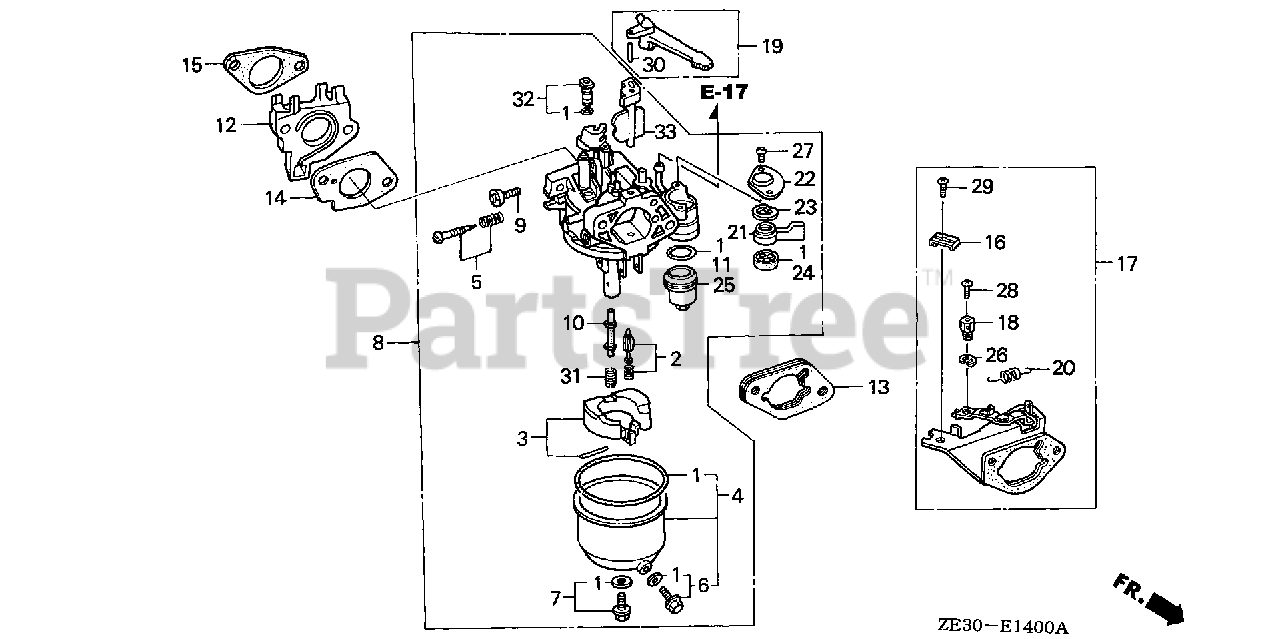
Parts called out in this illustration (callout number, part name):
1	GASKET SET (INCLUDES 16173-001-004)
2	VALVE SET, FLOAT
3	FLOAT SET
4	CHAMBER SET, FLOAT
5	SCREW SET, PILOT
6	SCREW SET, DRAIN
7	SCREW SET
8	CARBURETOR ASSY. (BE30B E)
9	SCREW, THROTTLE STOP
10	NOZZLE, MAIN
11	GASKET, FUEL STRAINER CUP
12	INSULATOR, CARBURETOR
13	SPACER, CARBURETOR
14	GASKET, CARBURETOR
15	GASKET, INSULATOR
19	LEVER, CHOKE (STD)
21	LEVER, VALVE
22	PLATE, LEVER SETTING
23	SPRING, PETCOCK LEVER
24	GASKET, PETCOCK
25	CUP, FUEL STRAINER
27	SCREW, PAN (3X8)
30	PIN, SPRING (2X12)
31	JET, MAIN (#92)
31	JET, MAIN (#95)
31	JET, MAIN (#98)
32	JET SET, PILOT (#35)
